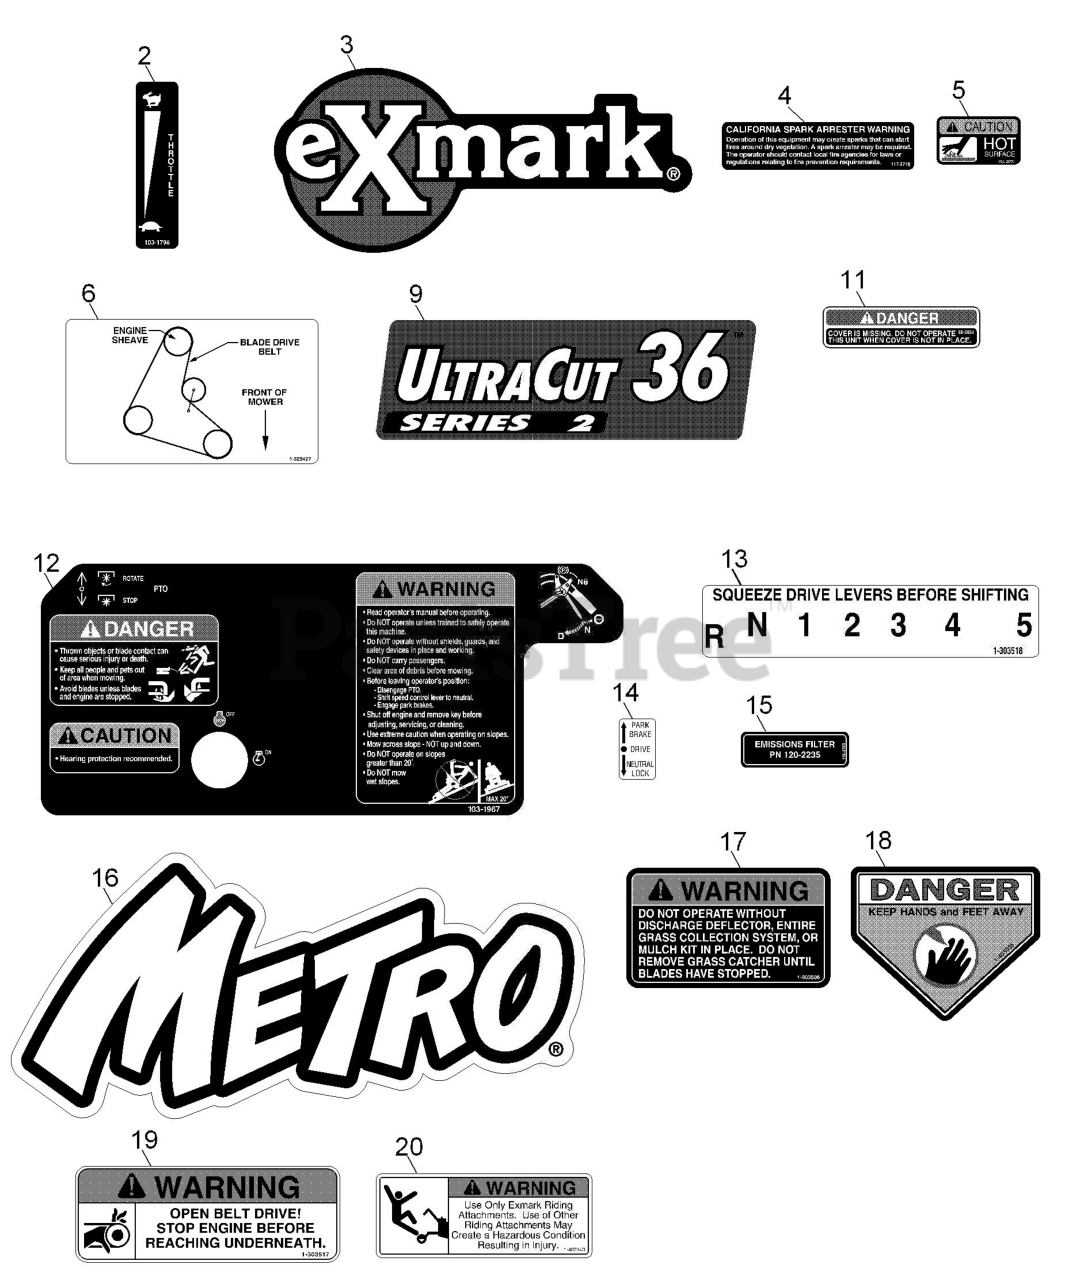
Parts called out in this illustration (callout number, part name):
2	DECAL,THROTTLE ONLY
3	DECAL,EXMARK LOGO
4	DECAL-ARRESTER, SPARK
5	DECAL-CAUTION
6	DECAL,BELT ROUTING 32/36
9	DECAL-ULTRACUT 36 SERIES
11	DECAL-COVER, MISSING
12	DECAL,CONSOLE
13	DECAL,SHIFTER
14	DECAL,NEUTRAL/BRAKE
15	DECAL-FILTER, EMISSIONS
16	DECAL,METRO MODEL
17	DECAL-WARNING, DISCHARGE
18	DECAL-DANGER
19	DECAL,BELT DRIVE
20	DECAL,SULKY WARNING
